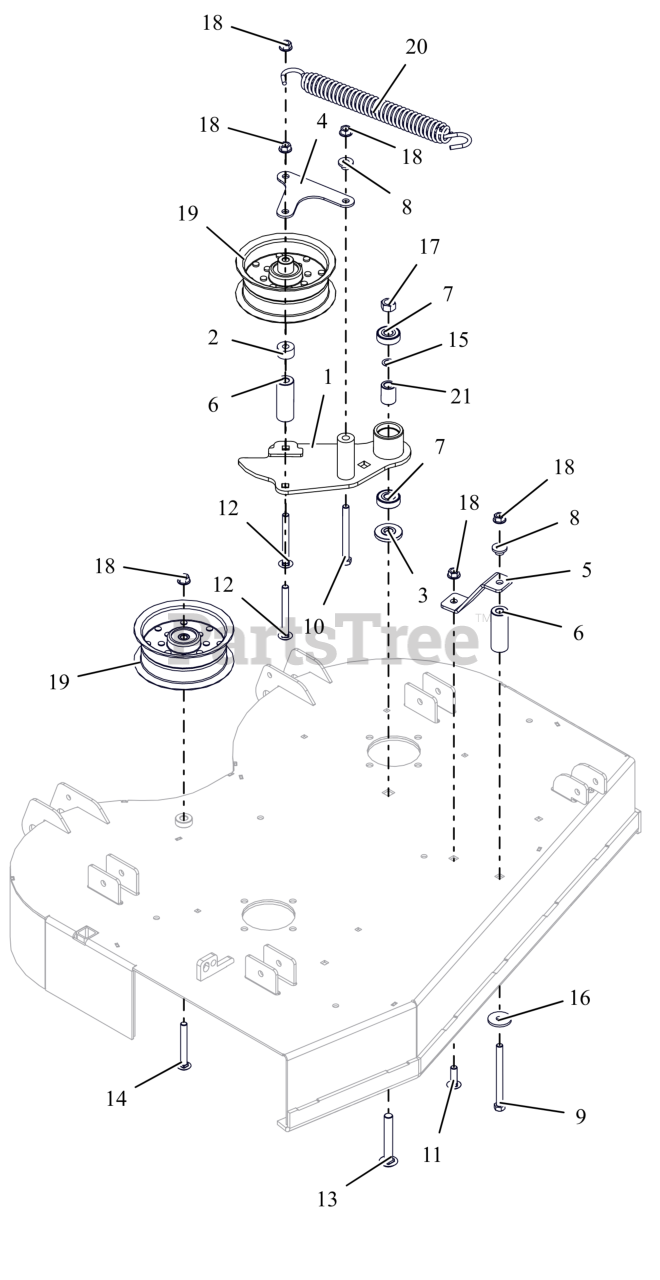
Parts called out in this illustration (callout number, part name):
1	WLDMT, IDLER ARM
2	SPACER .390X1.000X.562
3	SPACER, IDLER ARM
4	BRKT, SUPPORT (BLACK)
5	BRKT, SPRG ANCHOR (BLACK)
6	SPCR, TUBE (BLACK)
7	BRG-BALL .500X1.38X.437
8	BSHG-FLG .385X.500X.875X.406
9	BLT, HEX 0.375-16X4.25 GR5 ZCC
10	BLT, HEX 0.375-16X3.75 GR5 ZCC
11	BLT,RHSSN .38-16X1.25 G5 ZCC
12	BLT,RHSSN .38-16X3.50 G5 ZCC
13	BTL,RHSSN .500-13 X 3.25 G5 ZCC
14	BTL,RHSSN .375-16 X 3 G5 ZCC
15	WASHER, .500X.750X.020 THRUST
16	WSHR,FLT .406X1.375X.135 ZCC
17	NUT,LK-CTR .50-13 GA ZCC
18	NUT-LK-CTR-FLG .375-16 GF ZCC
19	PULLEY, FLAT 5.00X2.36X.375
20	SPRING, EXTENSION
21	SPACER .510 X .75 X 1.1485
